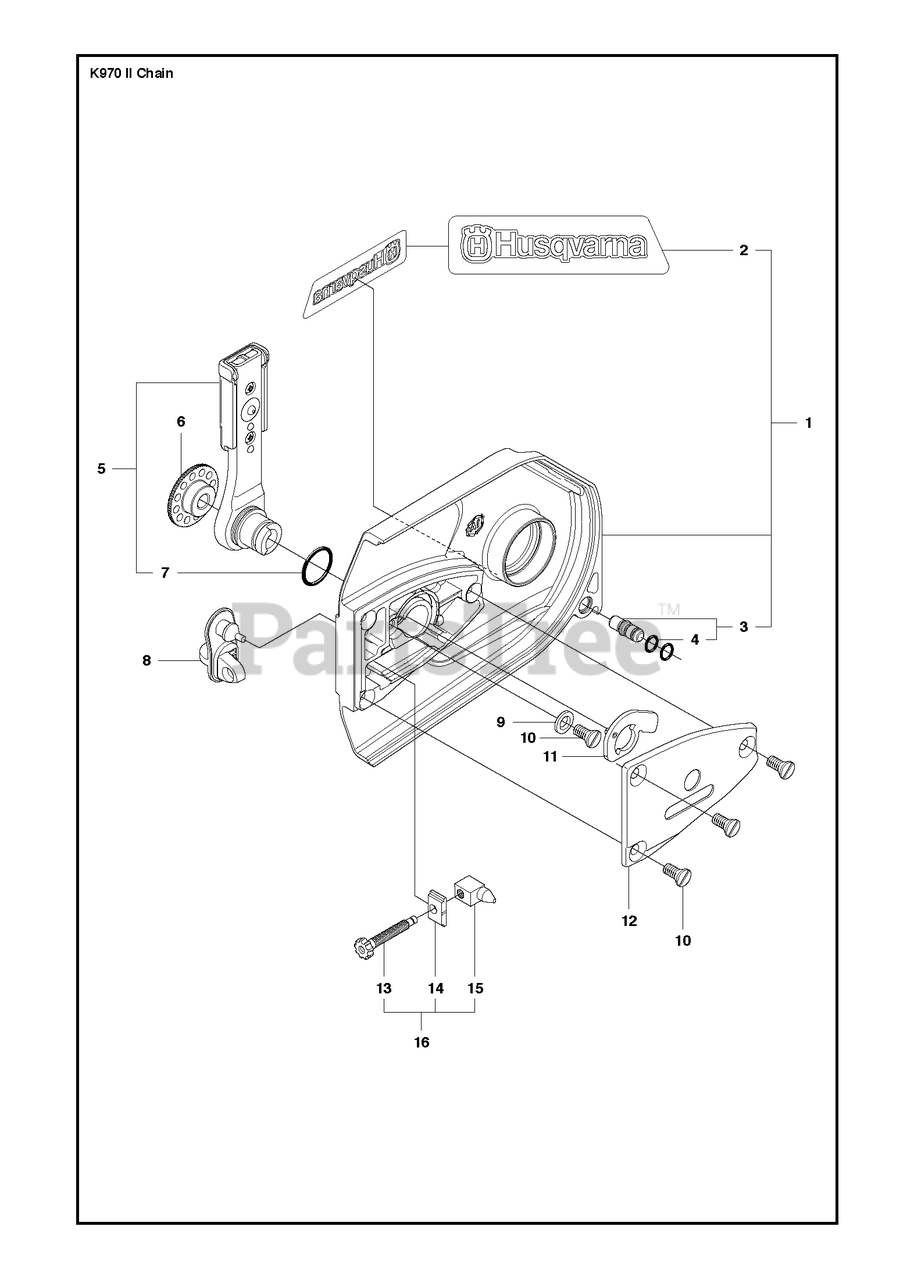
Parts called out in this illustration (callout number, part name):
1	CLUTCH COVERIncl. 2, 3
3	GUIDE PINIncl. 4
10	SCREW SLCSFM
